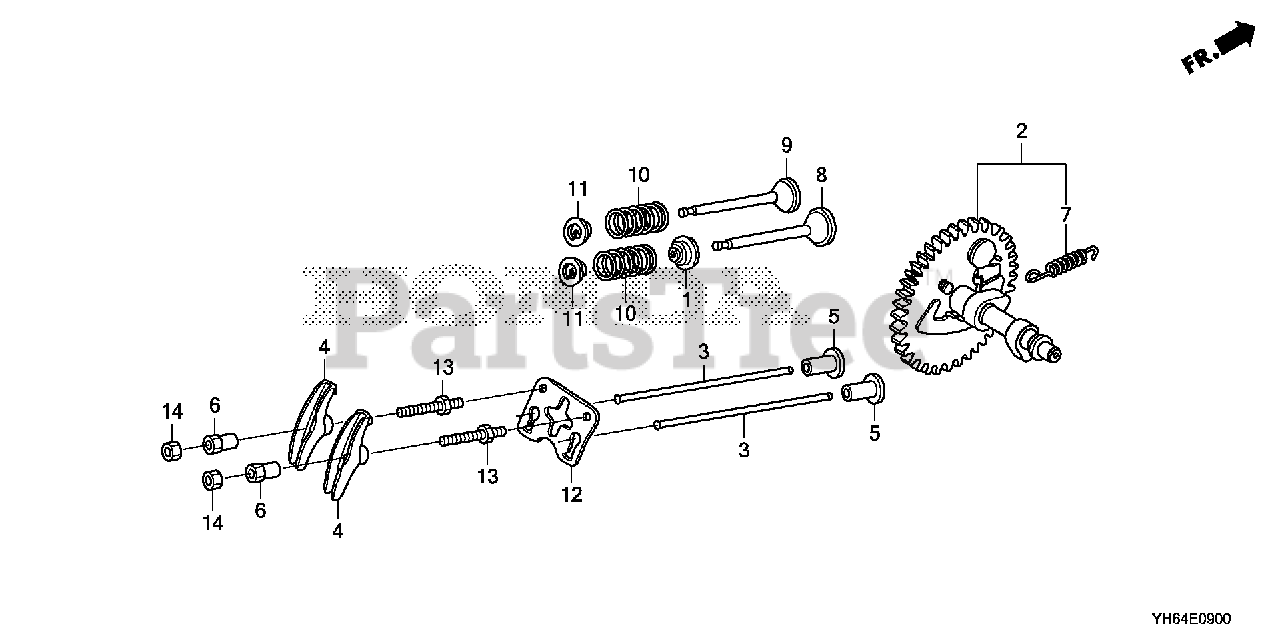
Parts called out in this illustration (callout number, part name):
1	SEAL, VALVE STEM
2	CAMSHAFT ASSY.
4	ARM, VALVE ROCKER
5	LIFTER, VALVE
6	PIVOT, ROCKER ARM
7	SPRING, WEIGHT RETURN
8	VALVE, IN.
9	VALVE, EX.
10	SPRING, VALVE
11	RETAINER, VALVE SPRING (EXHAUST SIDE)
12	GUIDE, PUSH ROD
13	BOLT, PIVOT (8MM)
14	NUT, PIVOT ADJ.
